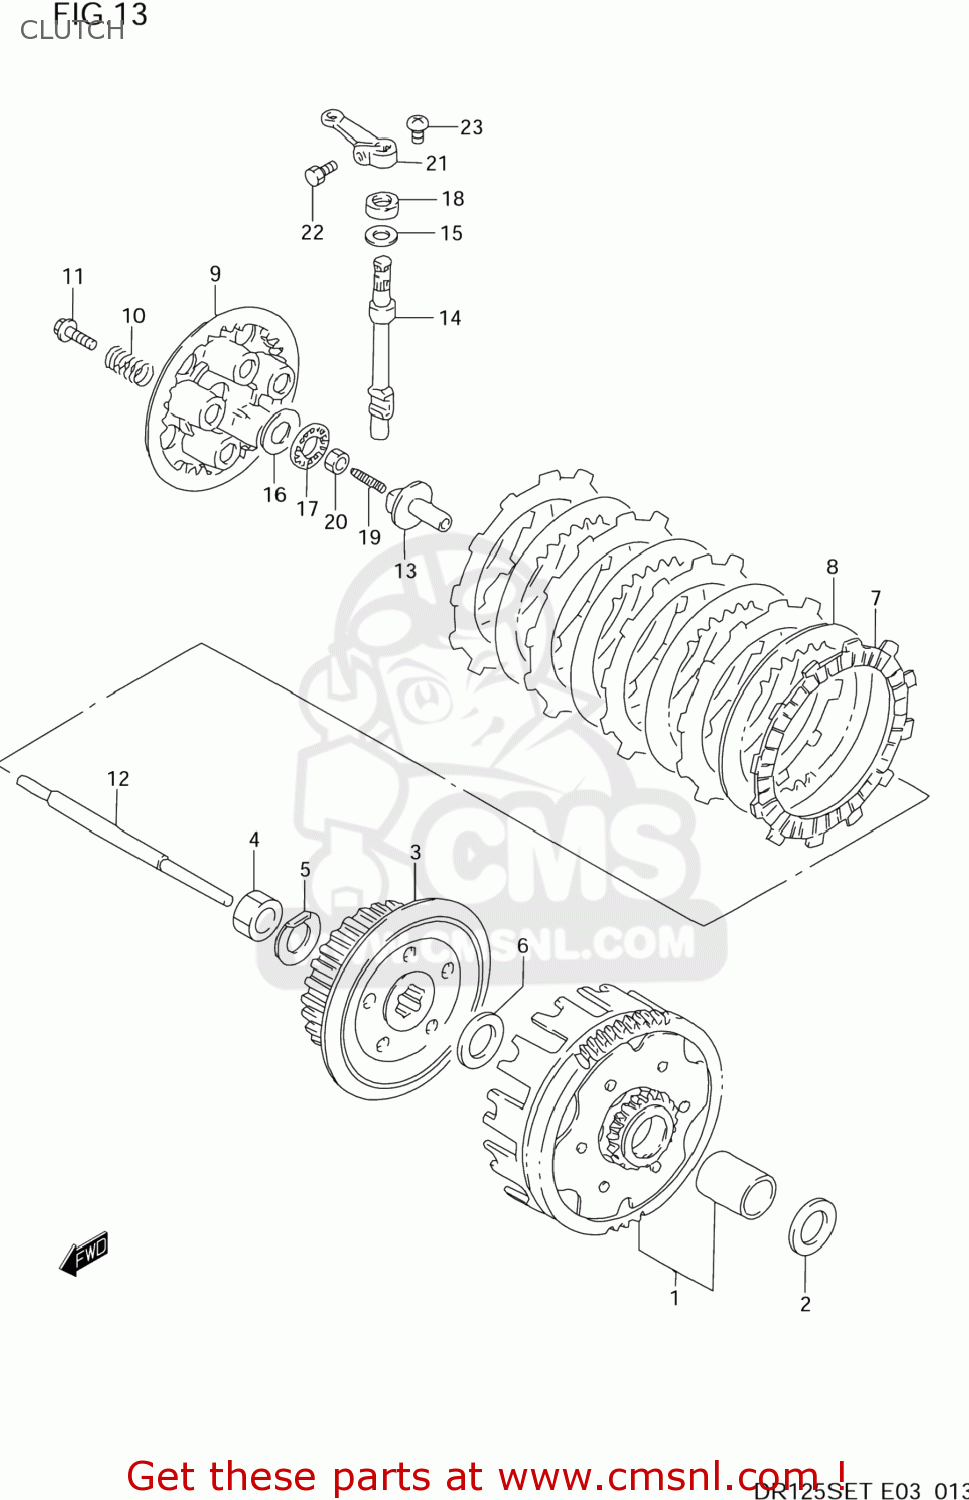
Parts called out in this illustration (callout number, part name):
1	GEAR ASSY,PRI DRIVEN(NT:59)
2	WASHER
3	HUB,CLUTCH SLEEVE
4	NUT
5	WASHER
6	WASHER
7	PLATE,CLUTCH DRIVE (NAS)
8	PLATE,CLUTCH DRIVEN (NAS)
9	PLATE,CLUTCH PRESSURE
10	SPRING
11	BOLT 5X16
12	ROD,CLUTCH PUSH
13	PIECE,CLUTCH PUSH
14	CAMSHAFT,CLUTCH RELEASE
15	WASHER,THRUST
16	WASHER(15.5X28X1)
17	BEARING(15X28X2)
18	SEAL,OIL(10X20X6)
19	SCREW(6X25)
20	NUT
21	ARM,CLUTCH RELEASE
22	BOLT
23	SCREW 6X10
